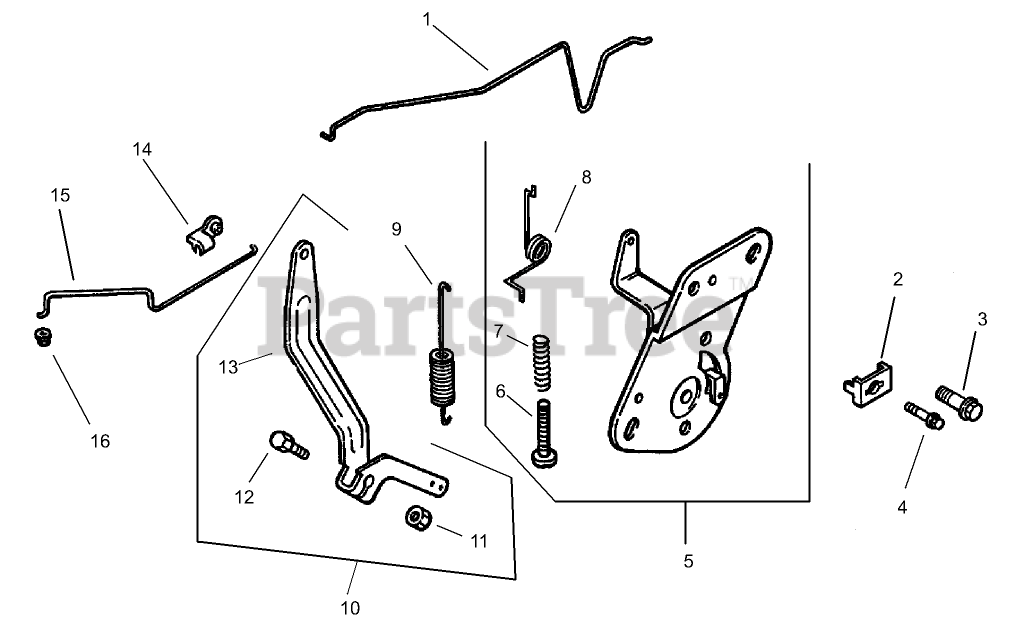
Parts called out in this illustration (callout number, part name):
1	Linkage-Choke
2	CLAMP-CABLE
3	SCREW-FLANGE, THREAD FORMING (M5X0.8X16)
4	Screw-Socket, 6 Lobed (Thread Forming, M6x1.0x20)
5	Control, speed assembly (Includes 6-8)
6	Screw-SPH,M4x0.7x25
7	Spring-Control, Speed
8	Spring-Return, Choke
9	Spring-Governor
10	Kit, Governor Lever (Incl 10-12)
11	Nut-Flange, Hex (1/4-20)
12	Bolt-Square Neck, Round Head (1/4-20x1)
13	Lever-Governor
14	BUSHING-RETAINING, LINKAGE
15	Linkage-Throttle
16	BUSHING-LINKAGE, THROTTLE
